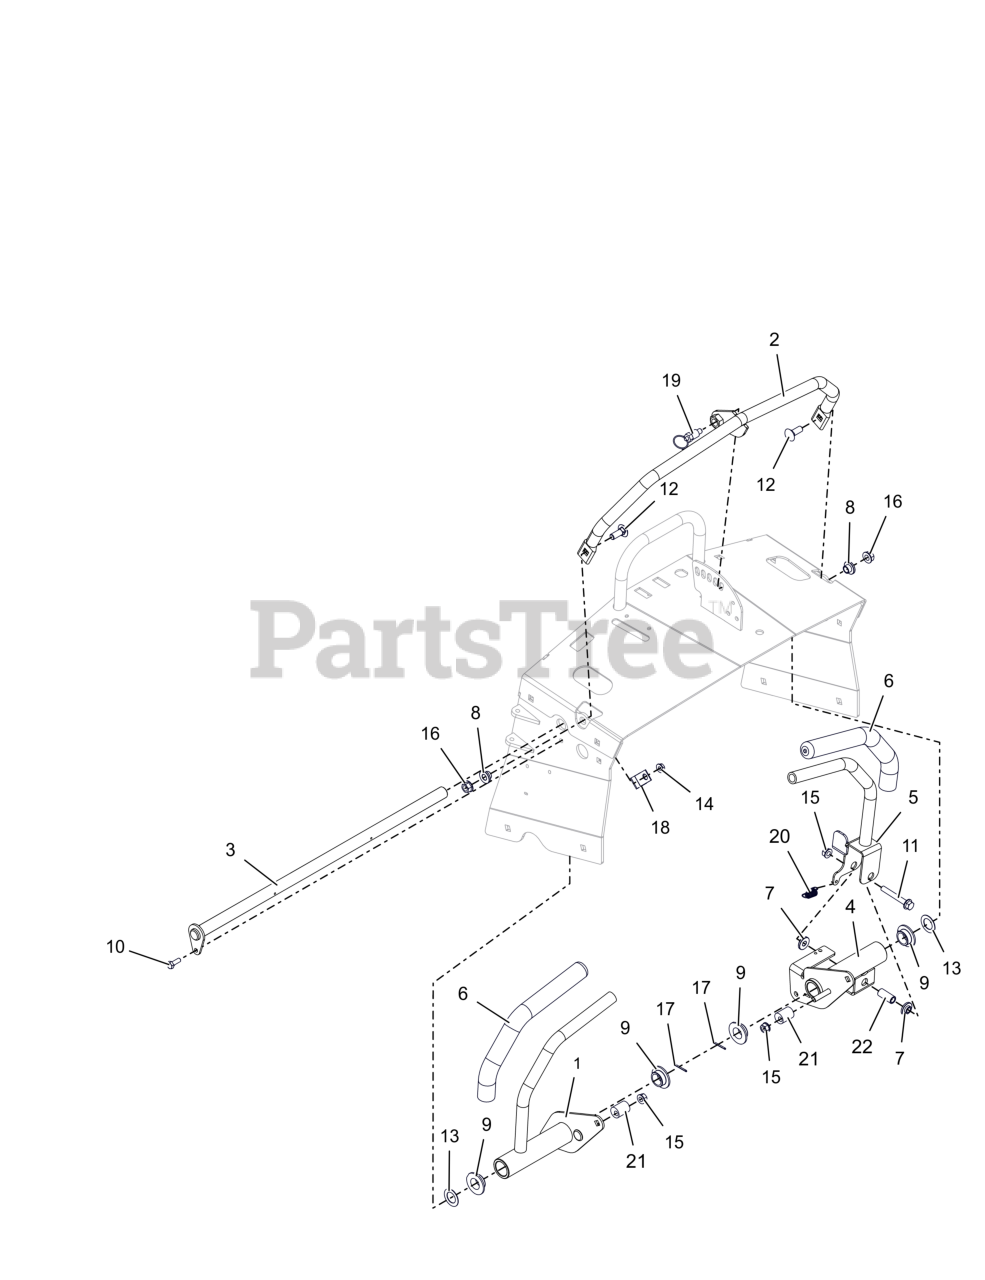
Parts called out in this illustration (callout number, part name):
1	WLDMT, RH STEERING CONTROL (BLACK)
2	WLDMT, SPEED CONTROL BAR (BLACK)
3	WLDMT, STEERING CONTROL PIVOT SHAFT
4	WLDMT-LH STEERING CNTRL PIVOT
5	WLDMT, LH STEERING CONTROL (BLACK)
6	GRIP, HANDLEBAR
7	BSHG, FLG .325X.499X.26X.88
8	BSHG-FLG .385X.500X.875X.406
9	BSHG-FLG .762X1.48X.44 IGLIDER
10	BLT, HEX .25-20X.75 G5 ZCC
11	BLT,HEX-FLG .31-18X2.25 G5 ZCC
12	BLT, RHSN .38-16X1.00 G5 ZCC
13	WSHR, FLT .760X1.225X.032 ZCC
14	NUT-LK-CTR-FLG .25-20 ZC120
15	NUT,LK-CTR-FLG .31-18 GF ZCC
16	NUT-LK-CTR-FLG .375-16 GF ZCC
17	PIN-COTR .09X1.0 PL
18	J-CLAMP
19	PULL PIN,.50-13THDX.310 PLNGR
20	SPRING, EXT. .043X.438X1.64
21	ECCENTRIC
22	SPCR, .344 X .500 X 1.140
